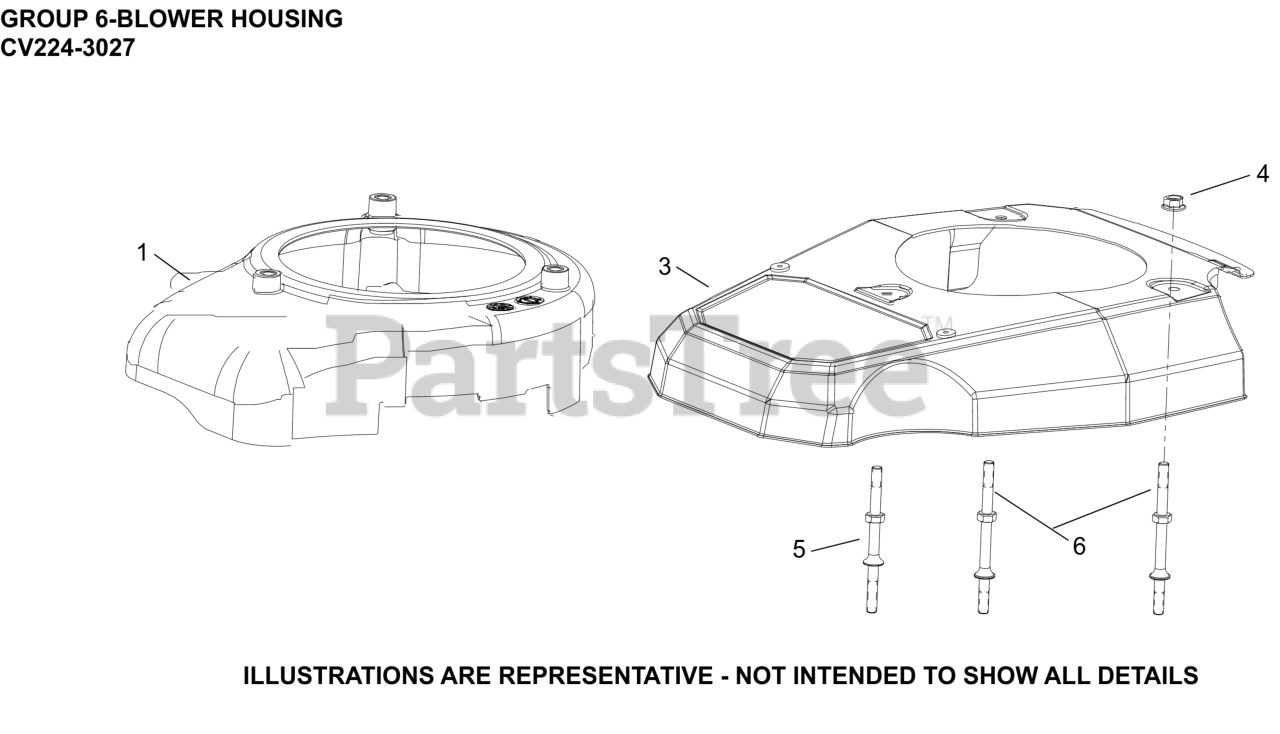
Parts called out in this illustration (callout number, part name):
1	KIT, BLOWER HOUSING
3	COVER, ENGINE
4	NUT, HEX FLANGE (M6) - USE 14 100 16-S
5	STUD-USE 14 072 25-S
6	STUD, BLOWER HOUSING
